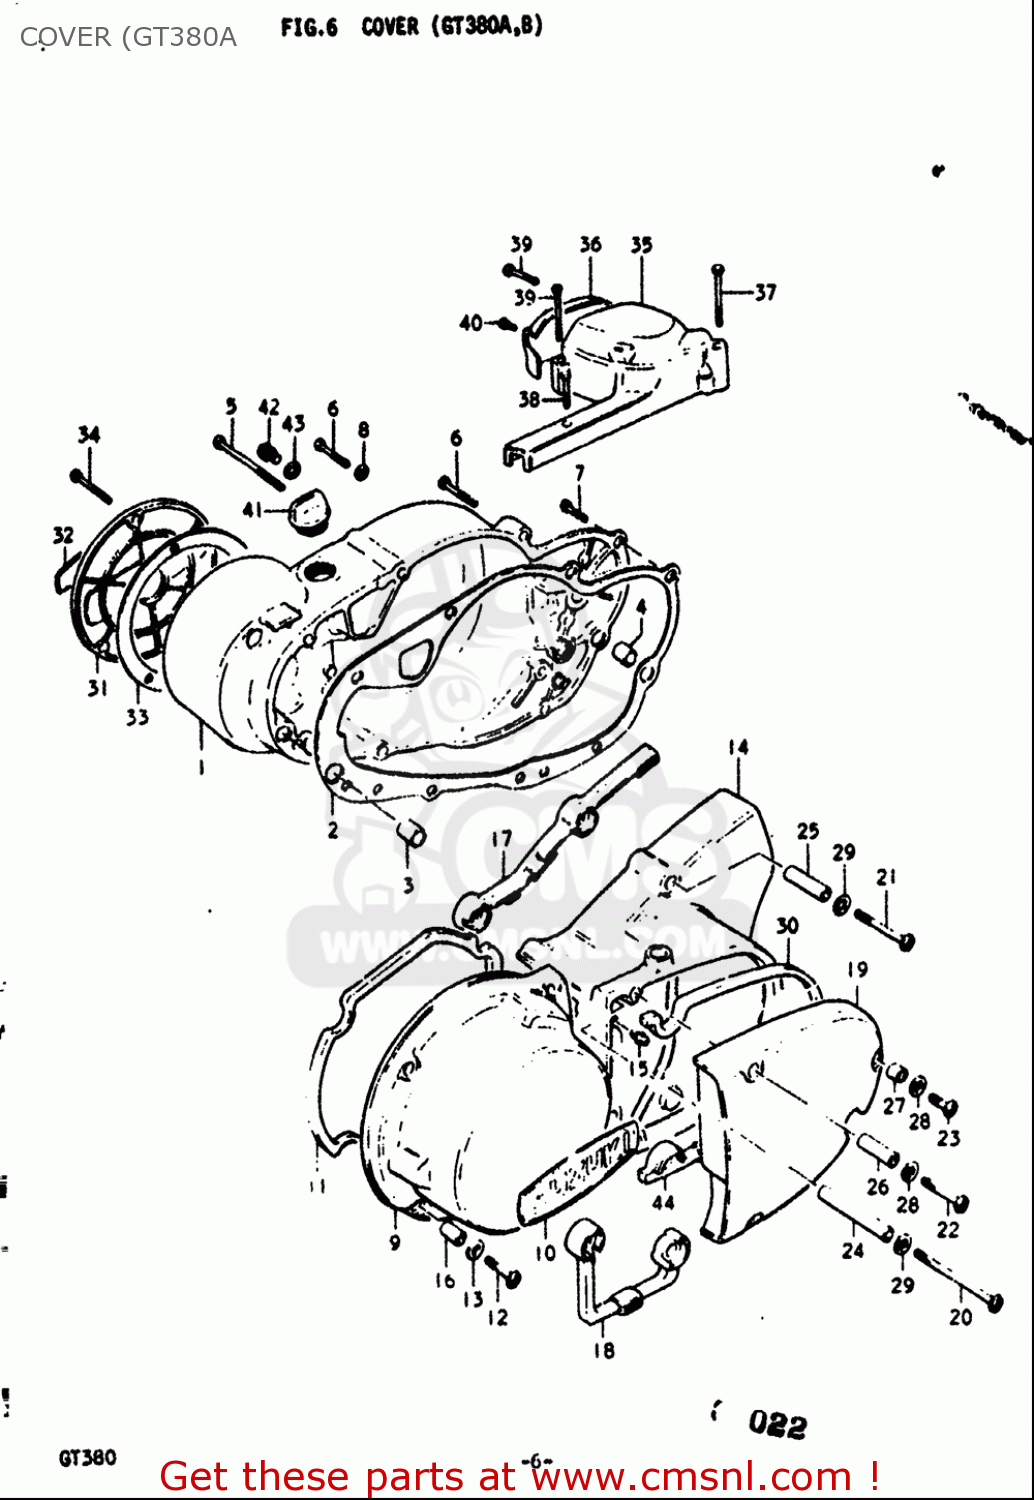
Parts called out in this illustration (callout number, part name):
2	GASKET,CLUTCH COVER (NAS)
3	PIN(10.4X13X22)
4	PIN
5	SCREW
6	SCREW
7	SCREW
8	WASHER(6.5X18X2)
10	EMBLEM,GENERATOR COVER
11	GASKET,MAGNETO COVER (NAS)
12	SCREW
13	WASHER
15	NIPPLE
16	SPACER(6.5X9X13.5)
18	CUSHION,ENGINE SPROCKET
20	SCREW
21	SCREW
22	SCREW
23	SCREW
24	SPACER
25	SPACER (6.4X9X33)
27	SPACER(5.5X8X7.5)
28	WASHER
29	WASHER
32	EMBLEM,CONTACT BREAKER CAP
33	GASKET,CONTACT BREAKER CAP (NAS)
34	SCREW
37	BOLT 5X45
38	BOLT
39	SCREW
40	SCREW
41	PLUG
42	SCREW(6X10)
43	GASKET(6.2X11X1) (NAS)
